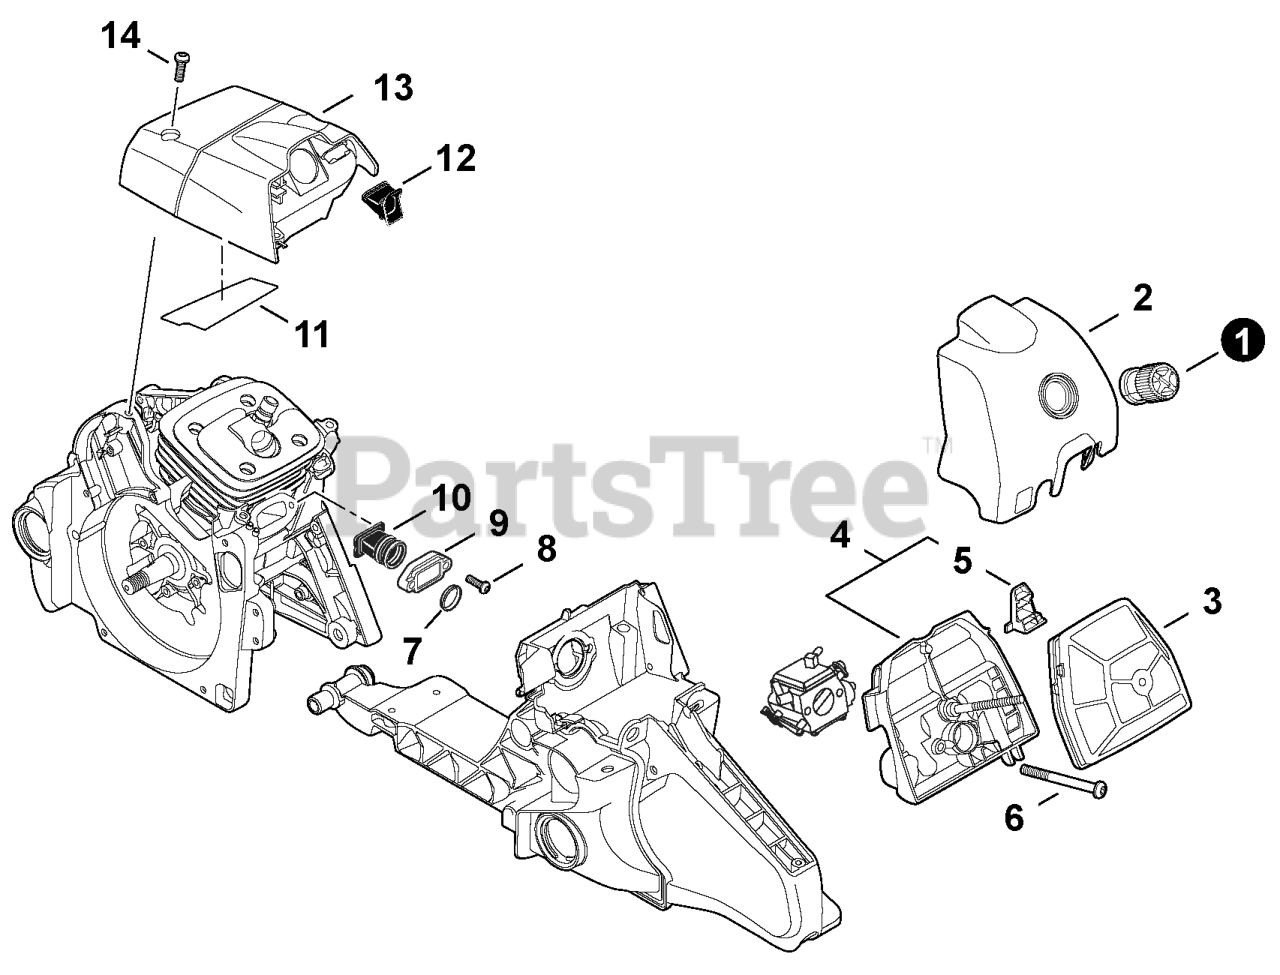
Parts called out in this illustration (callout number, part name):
1	KNOB, AIR FILTER COVER
2	COVER, AIR FILTER
3	FILTER ASSY, AIR
4	CASE, AIR FILTER
5	SHUTTER, AIR
6	BOLT, TORX 5x50
7	COLLAR 18.6x20.4x4
8	BOLT, TORX 5x16
9	HOLDER, BELLOWS
10	BELLOWS, INTAKE
11	SHIELD, HEAT 75x32x0.15
12	PIPE, INTAKE
13	COVER, ENGINE
14	BOLT, TORX 5x16
